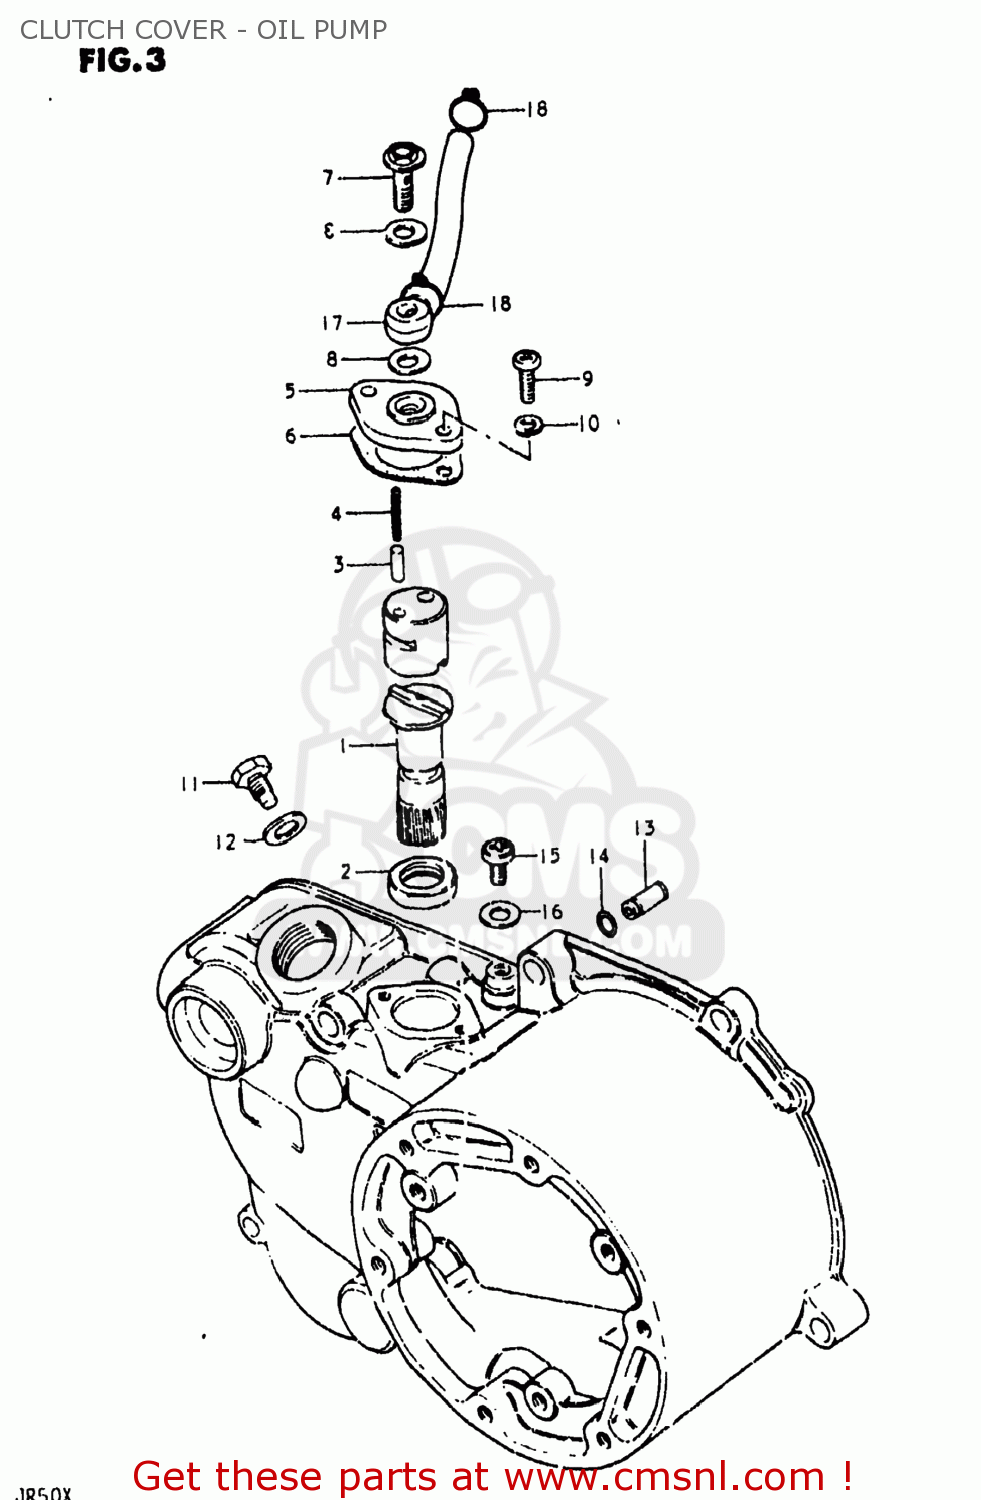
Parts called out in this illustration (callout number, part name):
1	GEAR,OIL PUMP DRIVE
2	SEAL,OIL(12X18.5X3)
3	PIN(2.3X7.5)
4	SPRING
5	CAM,OIL PUMP
6	GASKET,OIL PUMP (MCA)
7	UNION BOLT
8	GASKET(6.2X11X1).2 (NAS)
9	SCREW
10	LOCK WASHER
11	BOLT(6X10)
12	WASHER
13	VALVE,CRANK CHECK
14	O RING(D:1.05,ID:3.1)
15	SCREW
16	GASKET(5X9.5X1) (NAS)
17	HOSE,OIL NO.1
18	CLIP
